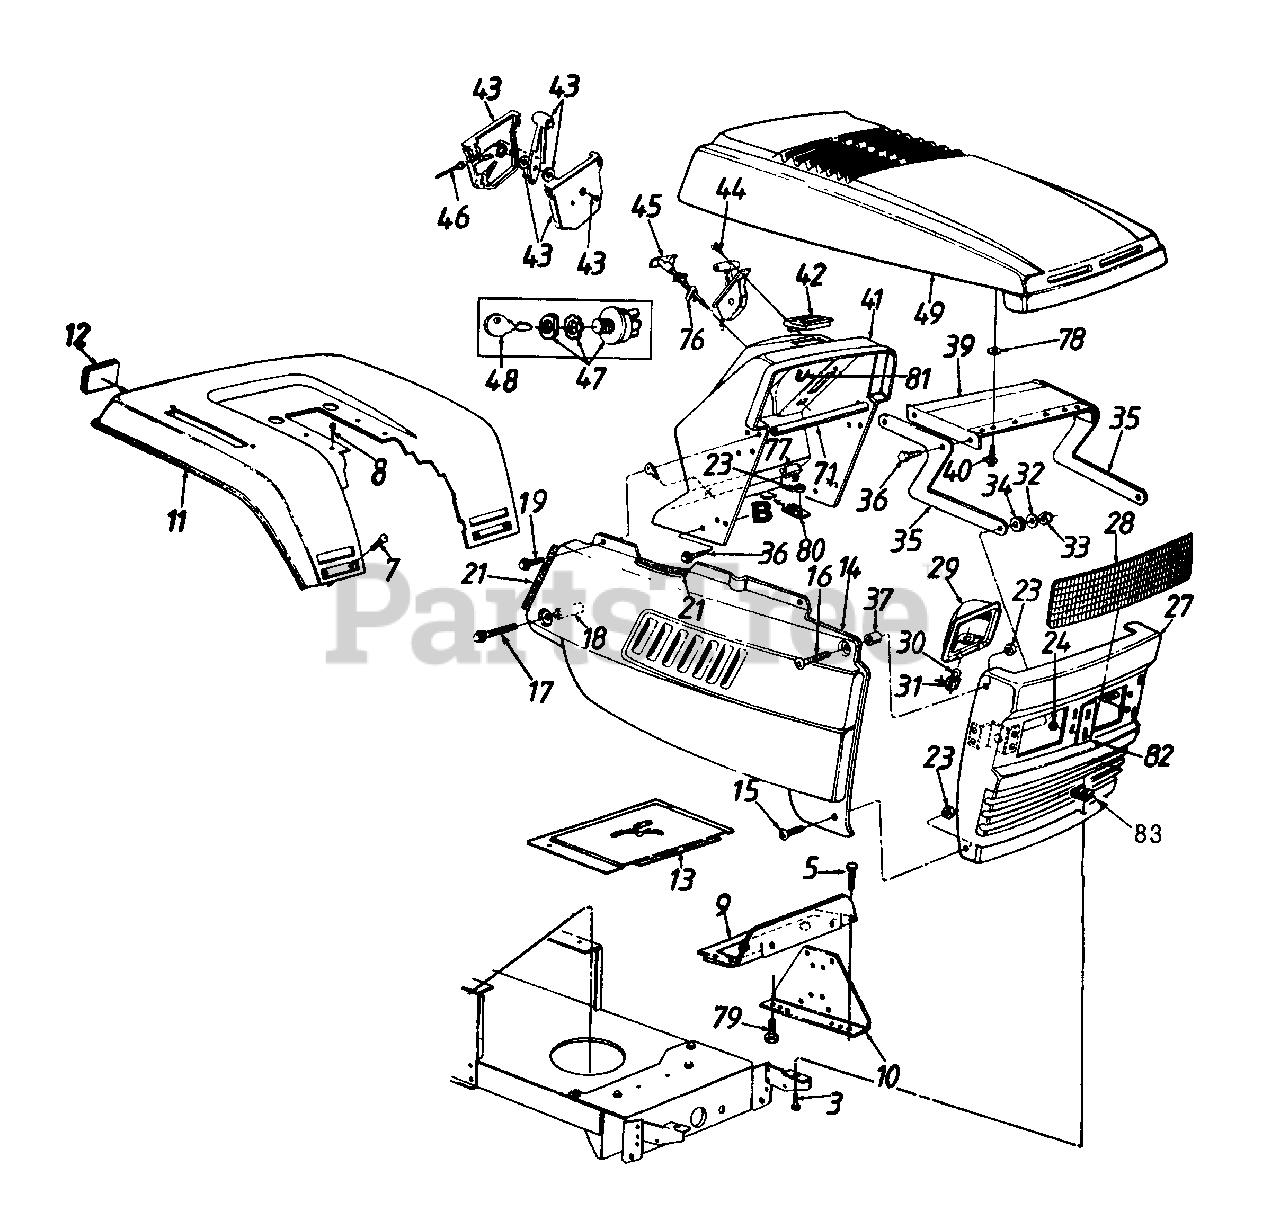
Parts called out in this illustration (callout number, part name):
3	Hex Bolt 5/16-18 x .75" Lg.
5	Hex Wash. Hd. Scr. 5/16" x .5" Lg.
7	Carriage Bolt 1/4-20 x .5" Lg.
8	Hex Wash. Hd. Tap Scr. 5/16 x .75" Lg.
16	Truss Mach. Scr. 1/4-20 x 1.0" Lg.
17	Hex Wash. TT-Tap Scr. 1/4-20 x 1.75" Lg.
18	Spacer .26" I.D. x 1.32"
19	Hex Rolling Tap Scr. 1/4-20 x .75" Lg.
21	Trim Strip - 18" Lg.
23	Hex Sems Nut 1/4-20 Thd.
24	Speed Nut 5/16" Thd.
29	Headlamp Housing
30	Headlamp
31	Twist Lock Lamp Socket
32	Bell-Wash. .345" I.D. x .88"
33	Hex L-Nut 5/16-18 Thd.
34	Rubber Washer
37	Spacer .262" I.D. x 31"
41	Dash
42	Ammeter
43	Throttle Control Box Ass'y
44	Mach. Scr #10 x 44" Lg.
45	Choke Control 23" Lg.
46	Throttle Control Wire 18 5" Lg.
47	Ignition Switch
48	Ignition Key
49	Hood - Red
71	Grille Support Tube
76	Choke Retainer
77	Light Switch
78	Fl-Wash .406" I.D. x .812" O.D.
79	Hex Bolt 1/4-20 x .88" Lg
80	Dash Fastening Tab
81	Cable Tie
82	Chrome Label
83	U-Nut 5/16-18 Thd
